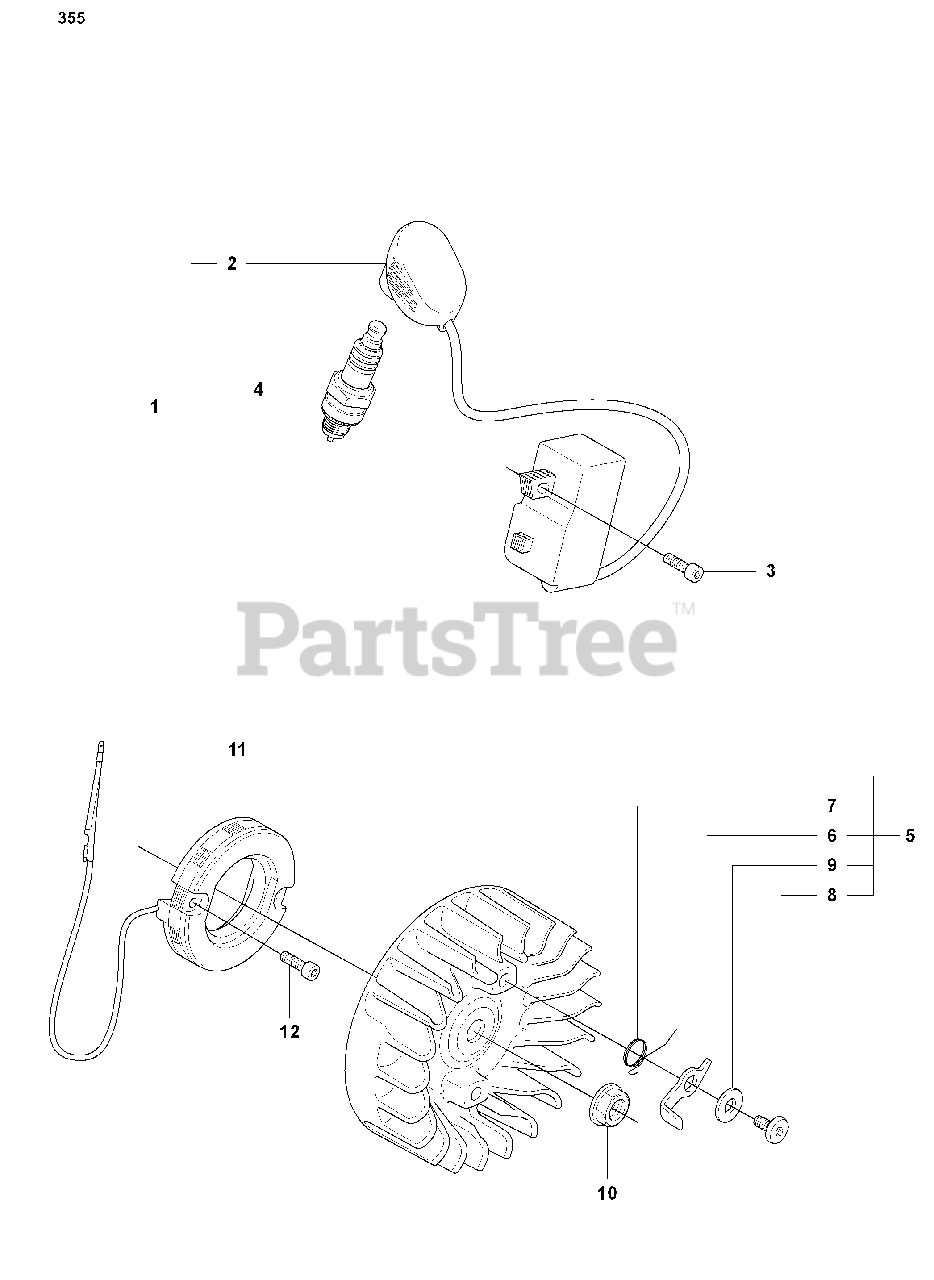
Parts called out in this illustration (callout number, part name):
2	SPARK PLUG CAP
4	BPMR7A NGK SPARK PLUG
6	STARTER PAWL
7	SPRING
10	NUT W/ WASHER
11	GENERATOR STARTER
12	SCREW
